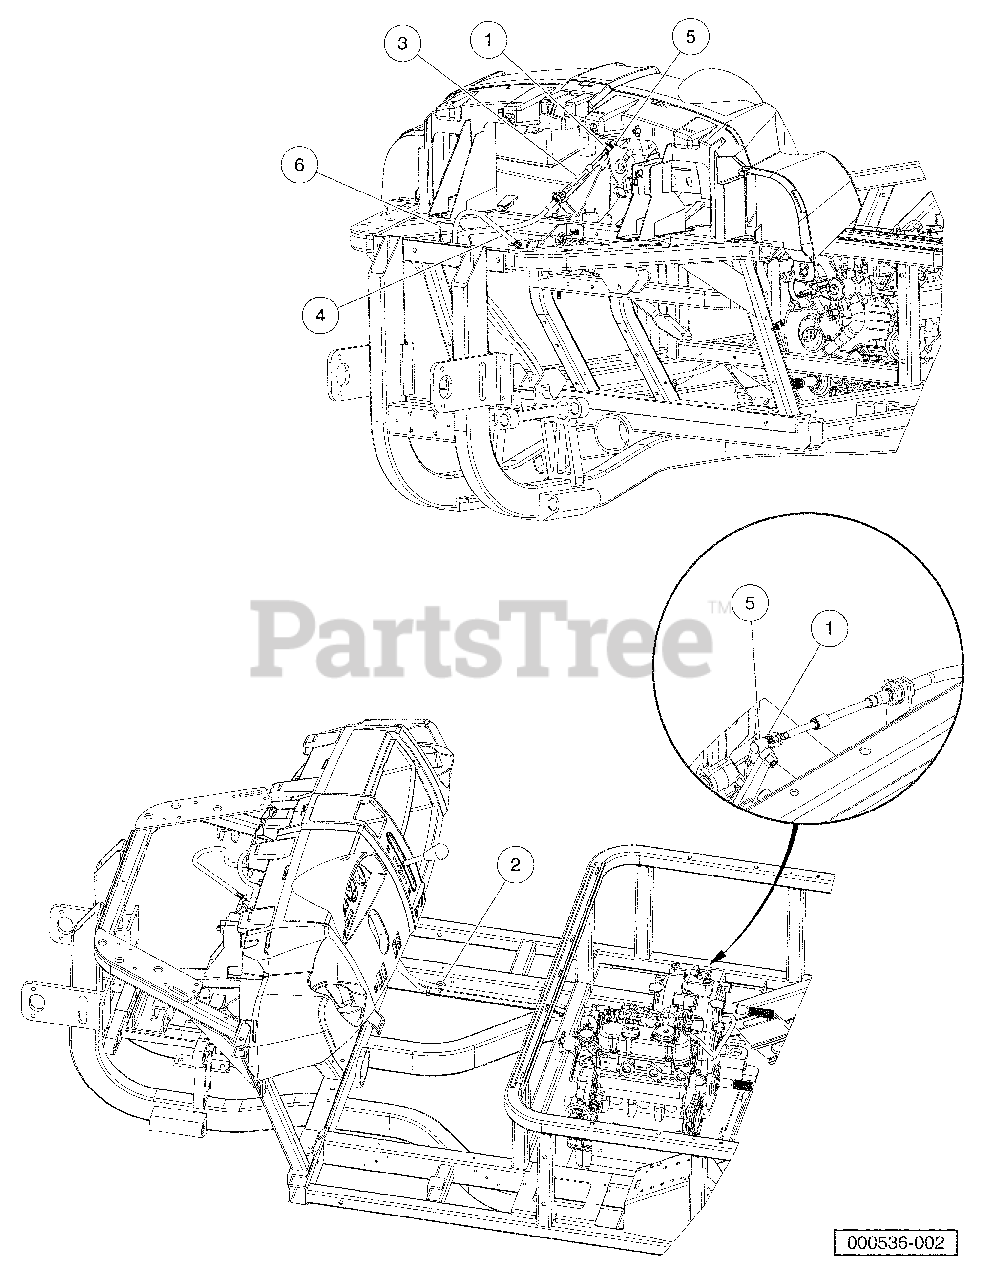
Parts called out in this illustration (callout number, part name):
1	Nut, 1/4-28 Hex Jam
2	Clip, Brake Line
3	Cable, Transmission Shift
4	Cable, Accelerator, Diesel
5	Joint, Ball, .346 Dia
6	Tie Wrap, 8" Nylon
